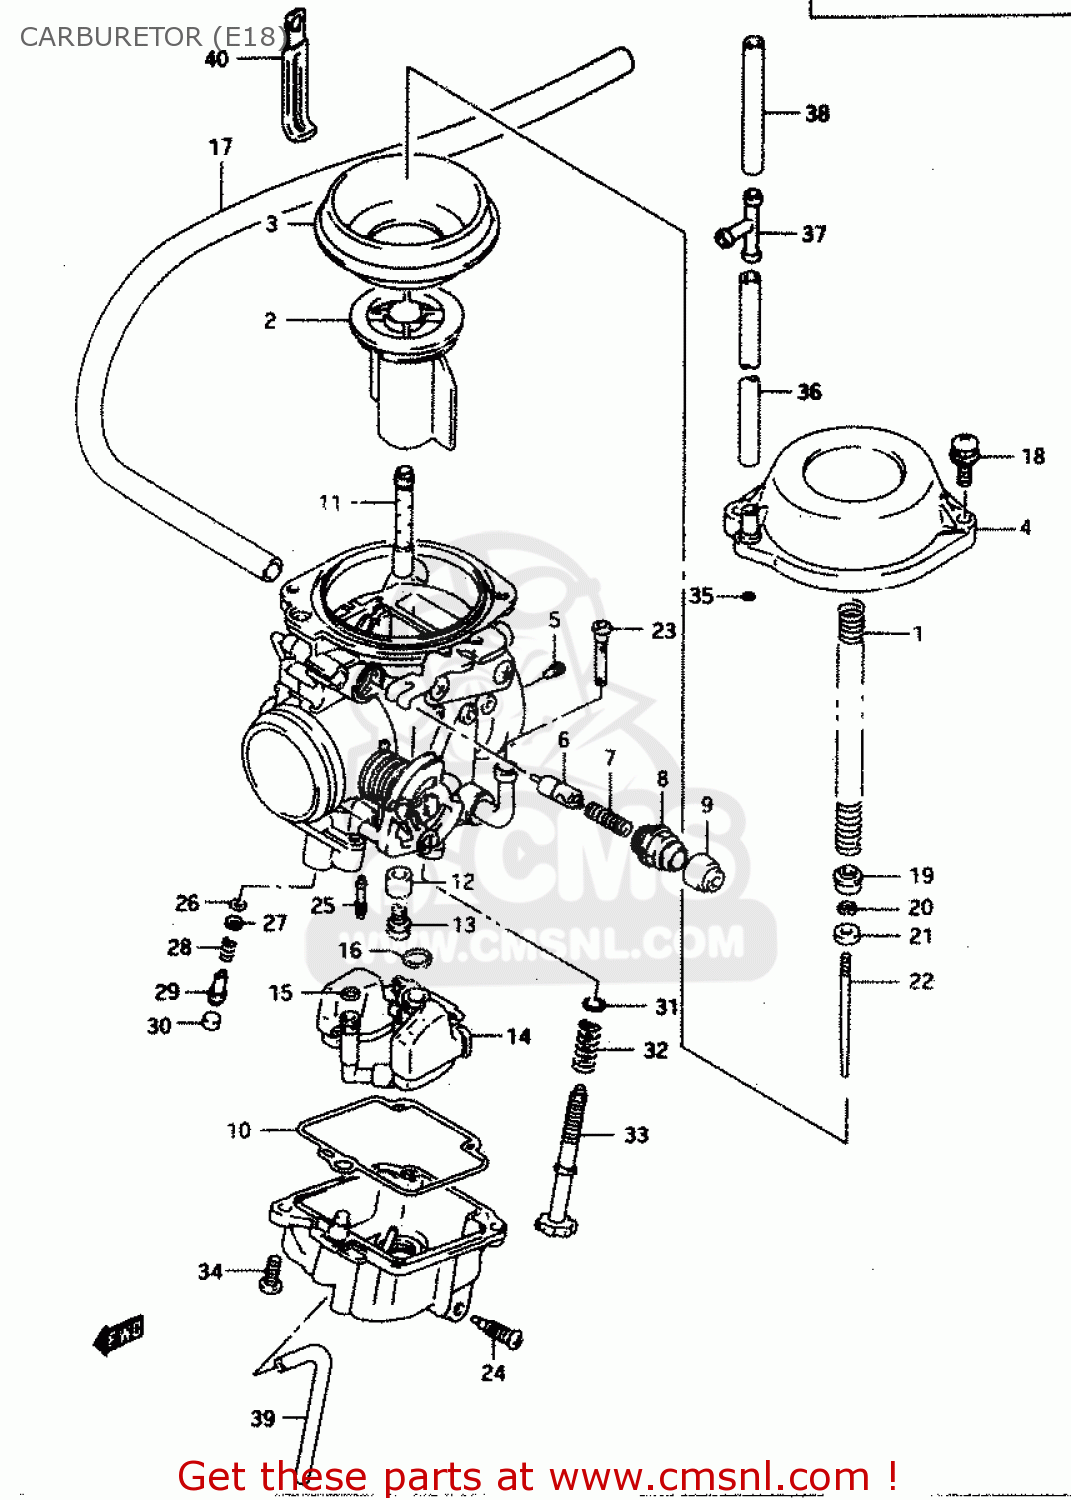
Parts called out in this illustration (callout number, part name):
1	SPRING
2	VALVE,PISTON
3	DIAPHRAGM
4	COVER,DIAPHRAGM
5	JET,AIR
6	PLUNGER
7	SPRING
8	HOLDER,GUIDE
9	CAP
10	GASKET,FLOAT CHAMBER (NAS)
11	JET,NEEDLE(Y-2)
12	RING
13	JET,MAIN(137.5)
14	FLOAT/NEEDLE VALVE ASSEMBLY
15	O RING
16	O-RING,NEEDLE VALVE
17	HOSE(6.5X11.5X600)
18	SCREW
19	RING
20	CLIP,NEEDLE
21	RING
22	NEEDLE,JET
23	FILTER
24	SCREW,DRAIN
25	JET,PILOT(52.5)
26	O RING,PILOT AIR SCREW
27	WASHER
28	SPRING
29	SCREW,PILOT
30	PLUG
31	WASHER
32	SPRING
33	ADJUSTER
34	SCREW(5X14)
35	O RING
36	HOSE (4.5X8.5X600)
37	JOINT,3 WAY
38	HOSE (4.5X8.5X600)
39	HOSE
40	CLAMP
